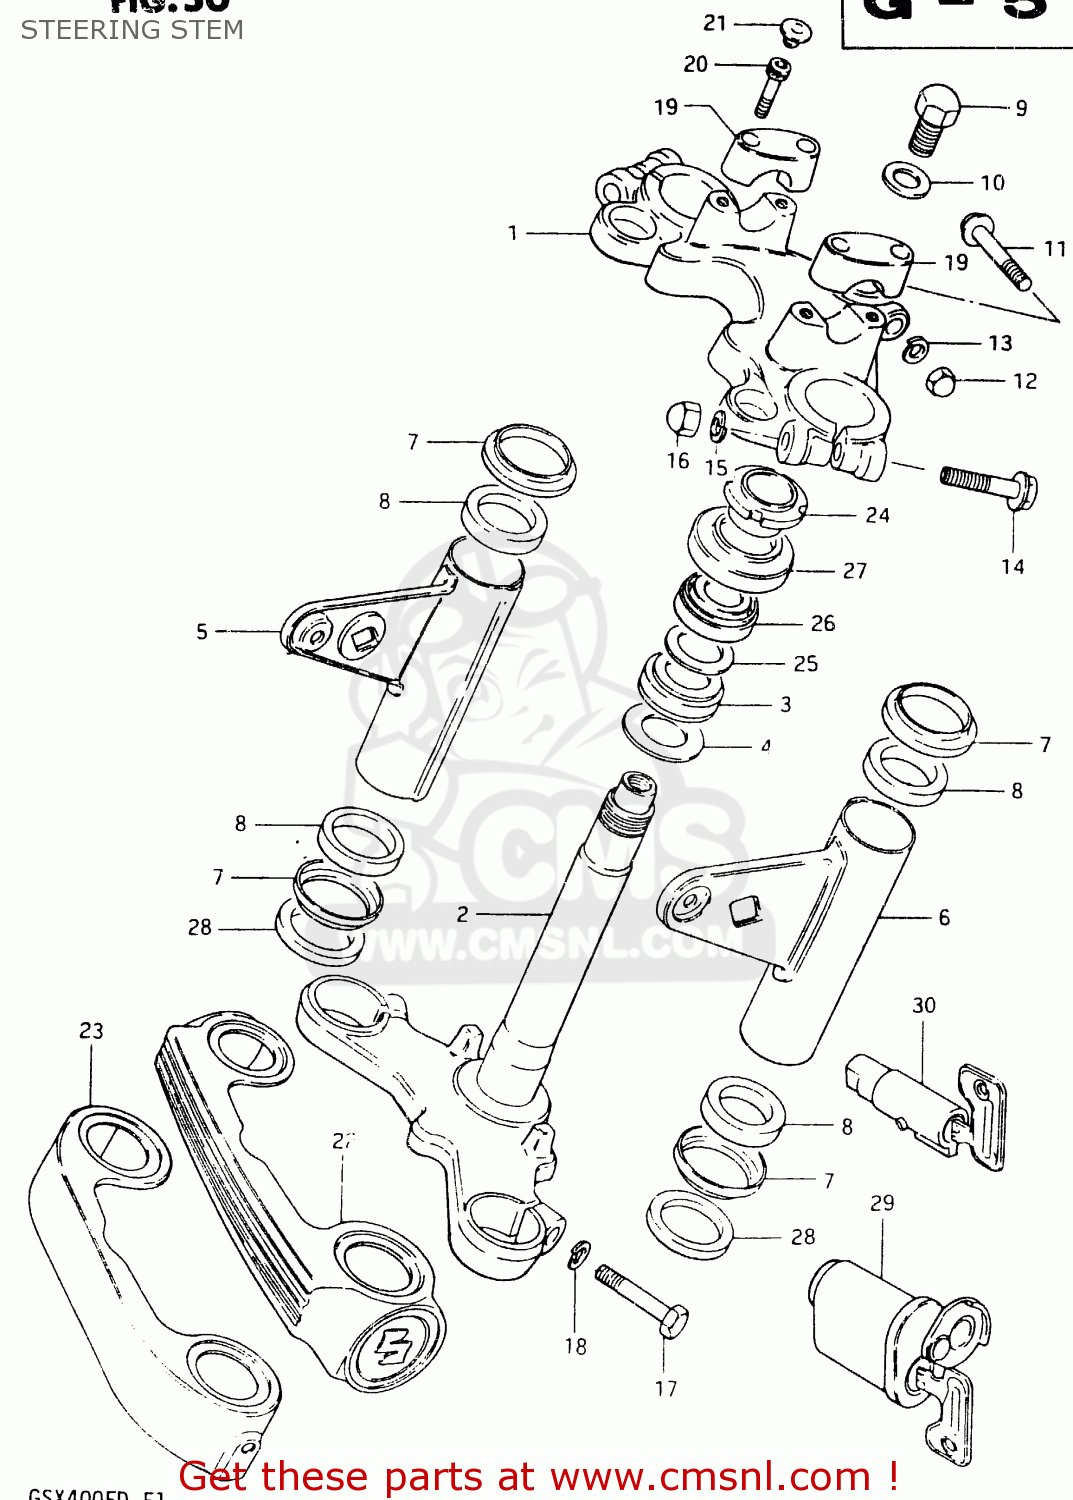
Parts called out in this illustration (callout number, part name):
1	HEAD,STEERING STEM
2	STEM,STEERING
3	BEARING
4	WASHER,THRUST
5	BRACKET,HEADLAMP,RIGHT
6	BRACKET,HEADLAMP,LEFT
7	CAP,HEADLAMP BRACKET
8	CUSHION,HEADLAMP BRACKET
9	BOLT 12X20
10	WASHER (12.5X26X1.6)
11	BOLT
12	NUT,M8X1.25X12
13	LOCK WASHER
14	BOLT 10X55
15	LOCK WASHER
16	NUT
17	BOLT 10X40
18	LOCK WASHER
19	HOLDER,HANDLEBAR(BLACK)
20	BOLT
21	CAP(OD:14.5)
22	COVER, FRONT FORK
23	COVER,FR FORK
24	NUT,STEERING STEM
25	WASHER(18.5X24X1)
26	TAPER,ROLLER BEARING
27	DUST SEAL,STEERING UPR
28	SEAT,HEADLAMP BRACKET LWR
29	LOCK ASSY, STEERING (NEIMAN TYPE EXECUTE
30	LOCK ASSEMBLY,STEERING (NEI
